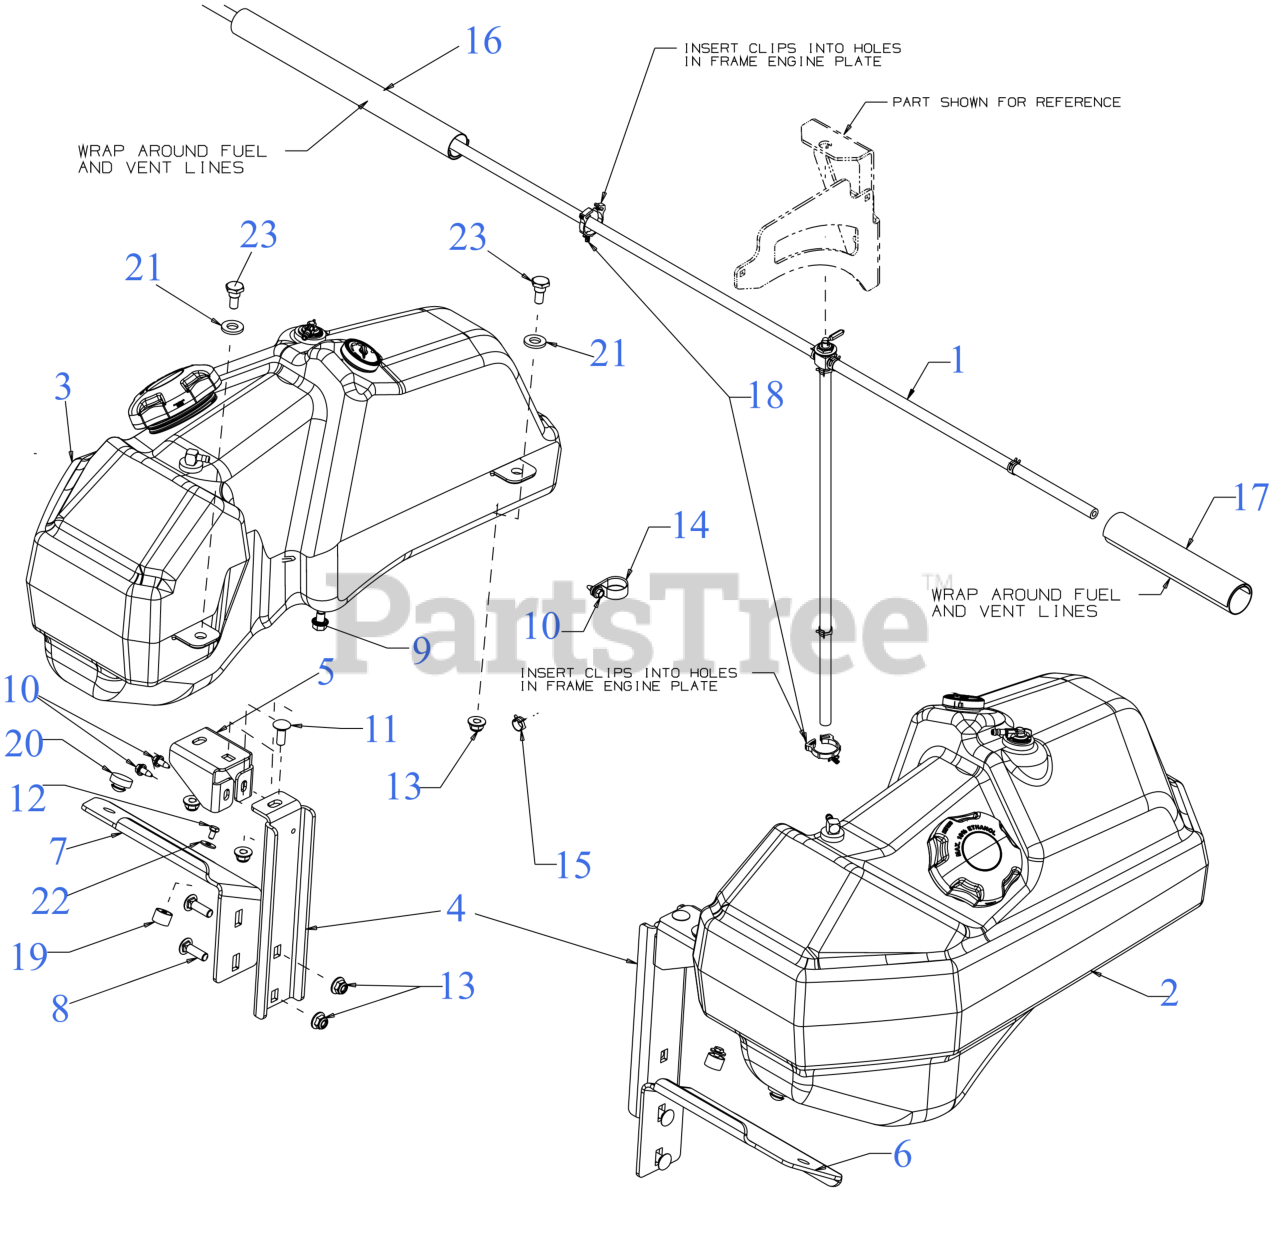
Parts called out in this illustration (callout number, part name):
1	FUEL HOSE W/VALVE EFI
1	HOSE CLAMP 1/20
2	FUEL TANK (7.25 GAL) (RH)
3	FUEL TANK (7.25 GAL) (LH)
4	FUEL TANK MOUNTING BRACKET
5	FUEL TANK MOUNTING BRACKET
6	LOWER FUEL TANK BRACKET (RH)
7	LOWER FUEL TANK BRACKET (LH)
8	CARRIAGE BOLT 3/8-16 X1.25 GR5
9	SCREW 3/8-16 x .500 GR5
10	SCREW 1/4-20X.625
11	CARRIAGE BOLT 3/8-16 x 1.00 GR5
12	SCREW M6-1.0X10MM GR8.8
14	DRAIN HOSE CLAMP
16	WRAP AROUND SLEEVE 14"
17	WRAP AROUND SLEEVE 8"
20	RUBBER BUMPER 1.000 x .313
21	FLAT WASHER .510 x 1.000 x .125
22	FLAT WASHER
23	SHOULDER SCREW .498 DIA x .340
